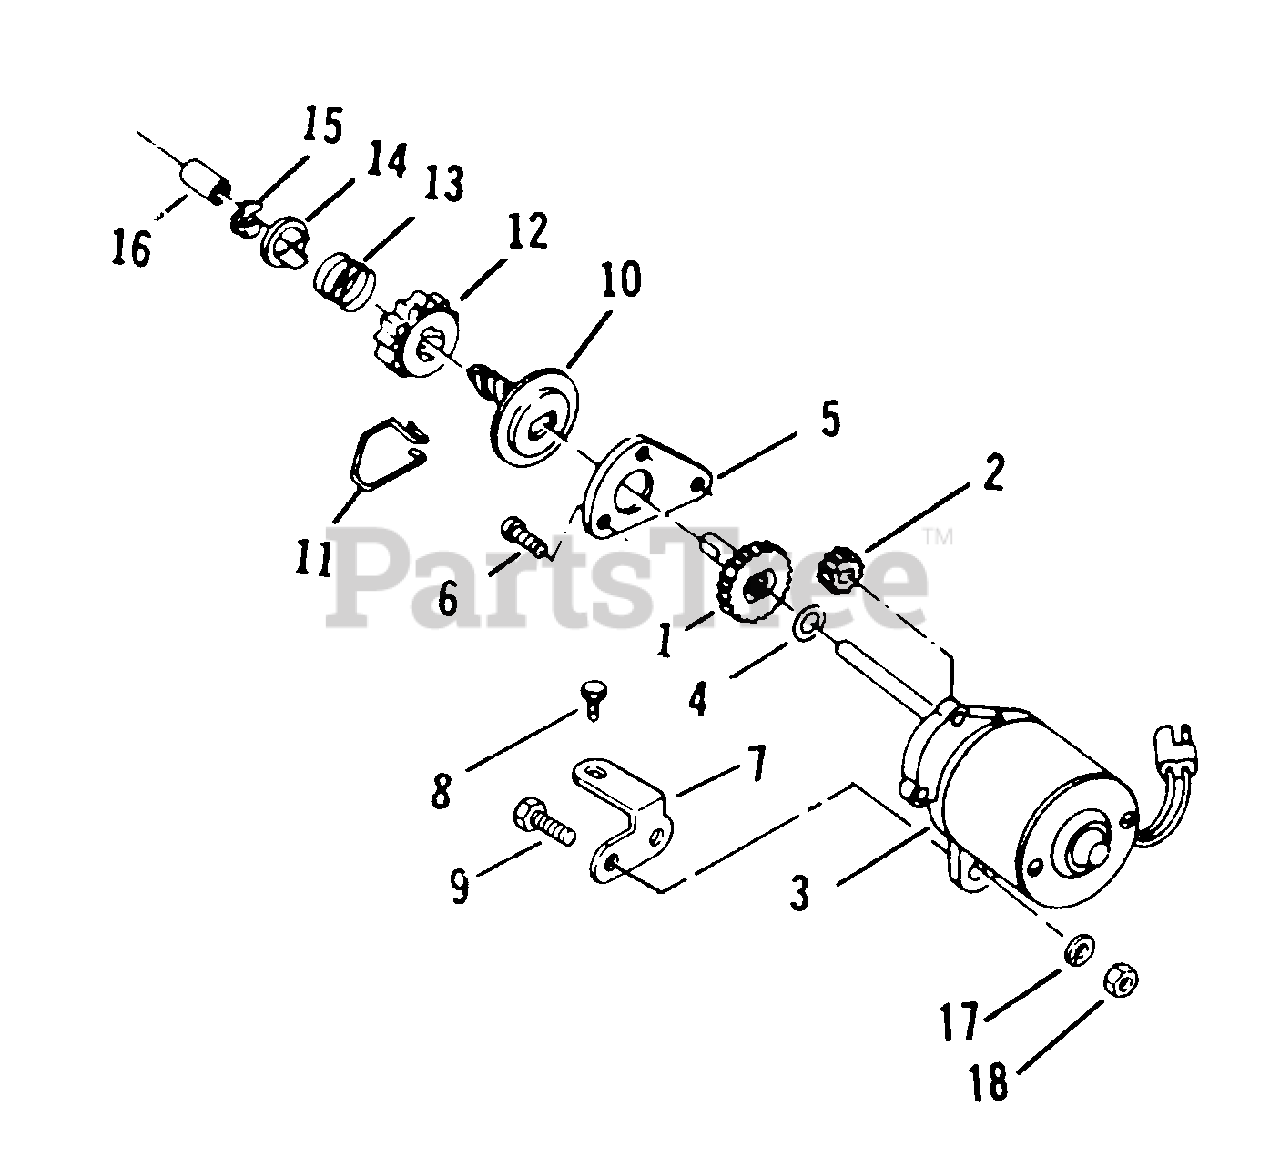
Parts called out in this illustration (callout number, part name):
1	Gear-Driven
2	Pinion-Motor Shaft
3	Motor Housing and Pin Assembly
4	Washer
5	Plate-Gear Cover
6	Screw
7	Bracket-Starter Mounting
8	Screw
9	Screw
10	Pinion, Spring and Clutch Assembly
11	Spring-Drag
12	Pinion
13	Spring-Pinion Return
14	Washer-Pinion Stop
15	Retaining Ring
16	Sleeve
17	Lockwasher
18	Nut
